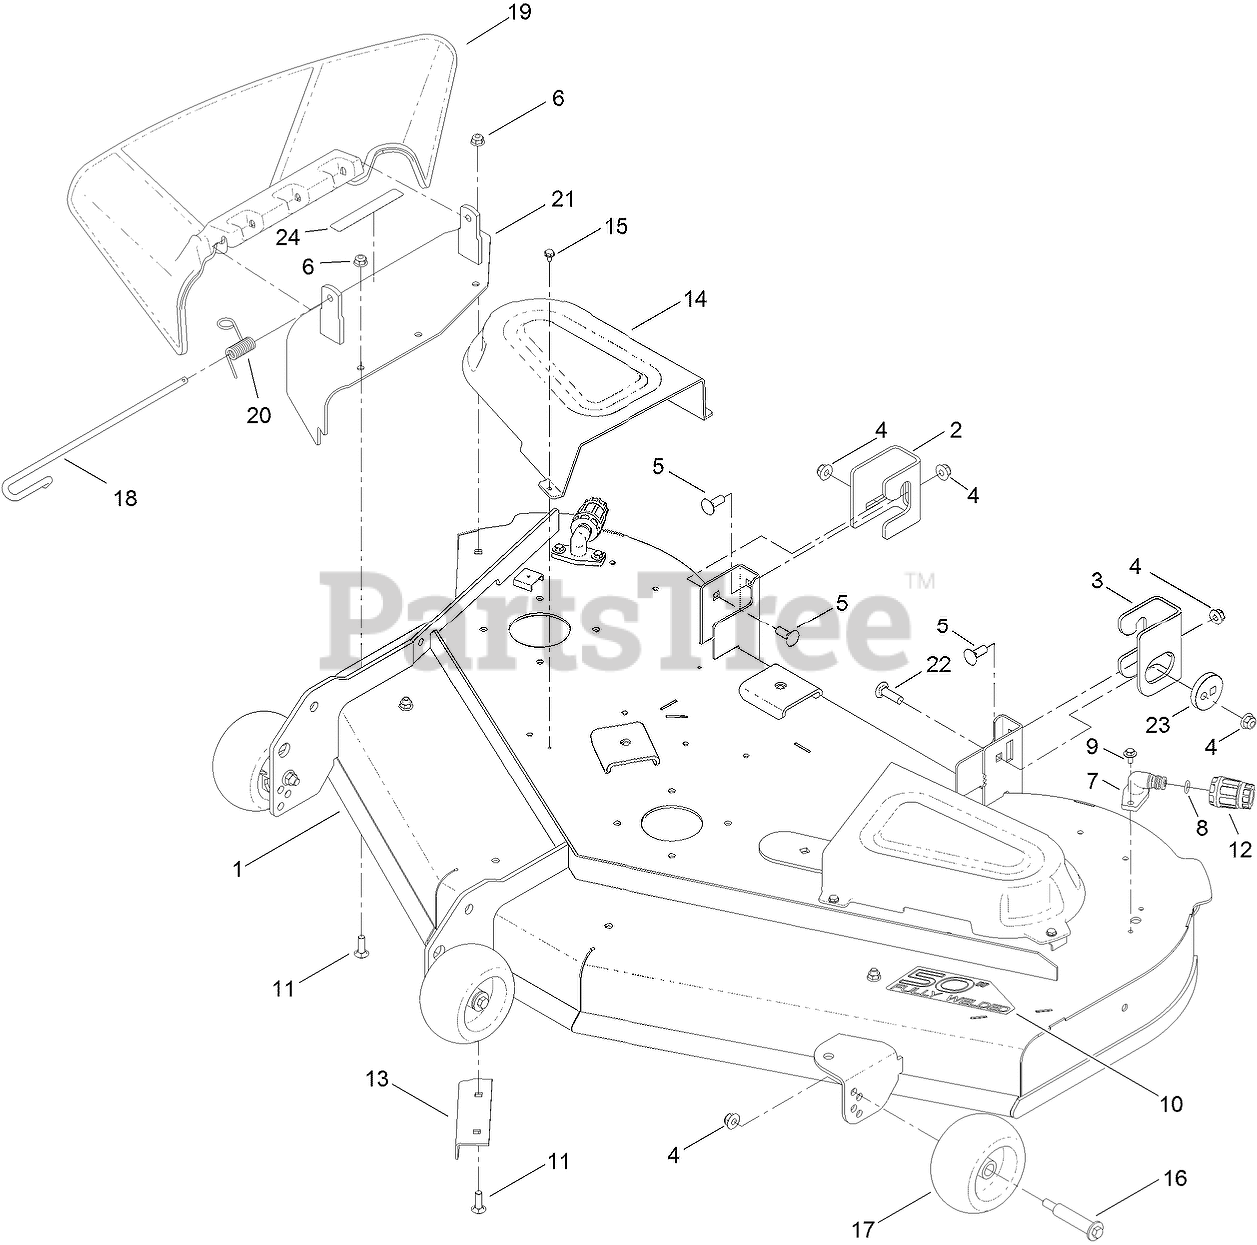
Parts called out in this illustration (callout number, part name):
1	50 INCH DECK AND DECAL ASM
2	BRACKET-HANGER, RH
3	BRACKET-HANGER, LH
4	NUT-HF, NI
5	BOLT-CARR
6	NUT-HF, NI
7	FITTING-WASHOUT
8	O-RING
9	SCREW-HHFTF
10	DECAL-DECK
11	SCREW-CARR
12	CONNECTOR-HOSE
13	BAFFLE-CUTOFF
14	COVER-BELT
15	SCREW-TAPTITE
16	BOLT-SHOULDER
17	ROLLER-SCALP, ANTI
18	PIN-CHUTE
19	DEFLECTOR-DISCHARGE
20	SPRING-TORSION
21	COVER-DISCHARGE
22	SCREW-CARR
23	ECCENTRIC
24	DECAL-DANGER
